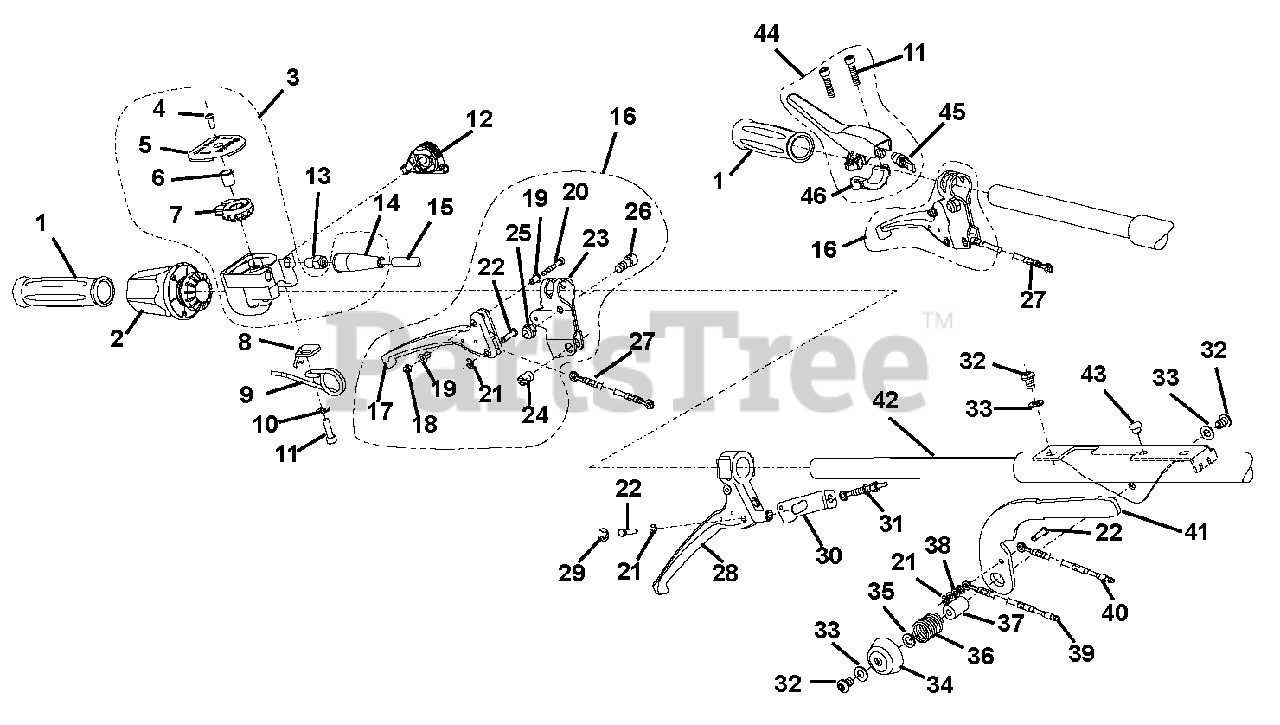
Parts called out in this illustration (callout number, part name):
1	Handle, Rubber
2	Bushing, Grip
3	MF Control Unit CPL (Includes 4 - 7 and 14)
4	Screw, M5 x 12
6	Bushing
7	Pinion Conical w/Cam
8	Cover, Stop
9	Spring, Pull Back
10	Washer, 6.1/14.2 x 1.4
11	Screw, M6 x 20
12	Lever, Throttle
13	Niupple, Screwed
15	Cable, Driving
16	Lever, CPL (Includes 17 - 26)
18	Nut, Lock M4
20	Screw, M4 x 30
21	Washer, Lock
22	Pin, Lock
23	Guide, Lever
24	Shaft, Stay
25	Nut, Lock M8
26	Screw, M8 x 16
27	Cable, Steering
28	Lever, CPL
29	Washer, Lock
31	Cable, Swivelling Handlebar
32	Screw, M8 x 12
33	Washer, Form S 8.2/16.2 x 1.4
35	Washer, 8.4 x 15
36	Spring, Pressure
37	Bushing w/Tread
38	Washer, 5.3 x 10 x 1
39	Cable, Handbrake Right
40	Cable, Handbrake Left
41	Lever, Brake
42	Bracket, Brake Assembly
43	Stop, Pressure Switch
44	Lever, Emergency
